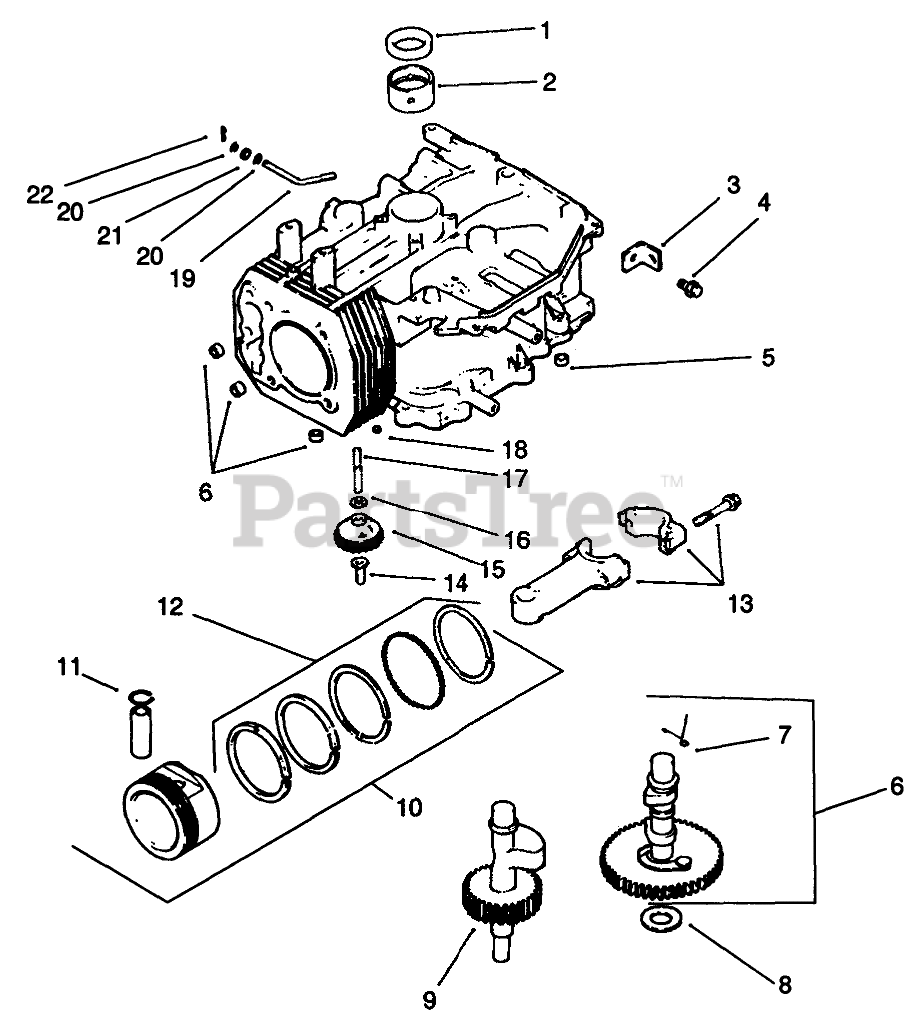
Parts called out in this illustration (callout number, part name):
1	Seal-Oil
2	Bearing-Crankshaft
3	Strap-Liting
5	Pin-Dowel
6	Camshaft Assembly
7	Spring-Actuating
8	Shim-Camshaft
9	Shaft-Balance
10	Piston W/Ring Set (Std.)
11	Retainer-Piston Pin
12	Ring Set (Std.)
13	Connecting Rod STD
14	Pin-Governor
15	Gear-Governor ASM
17	Shaft-Govenor Gear
19	Rod-Push
21	Seal
22	Pin-Hitch
